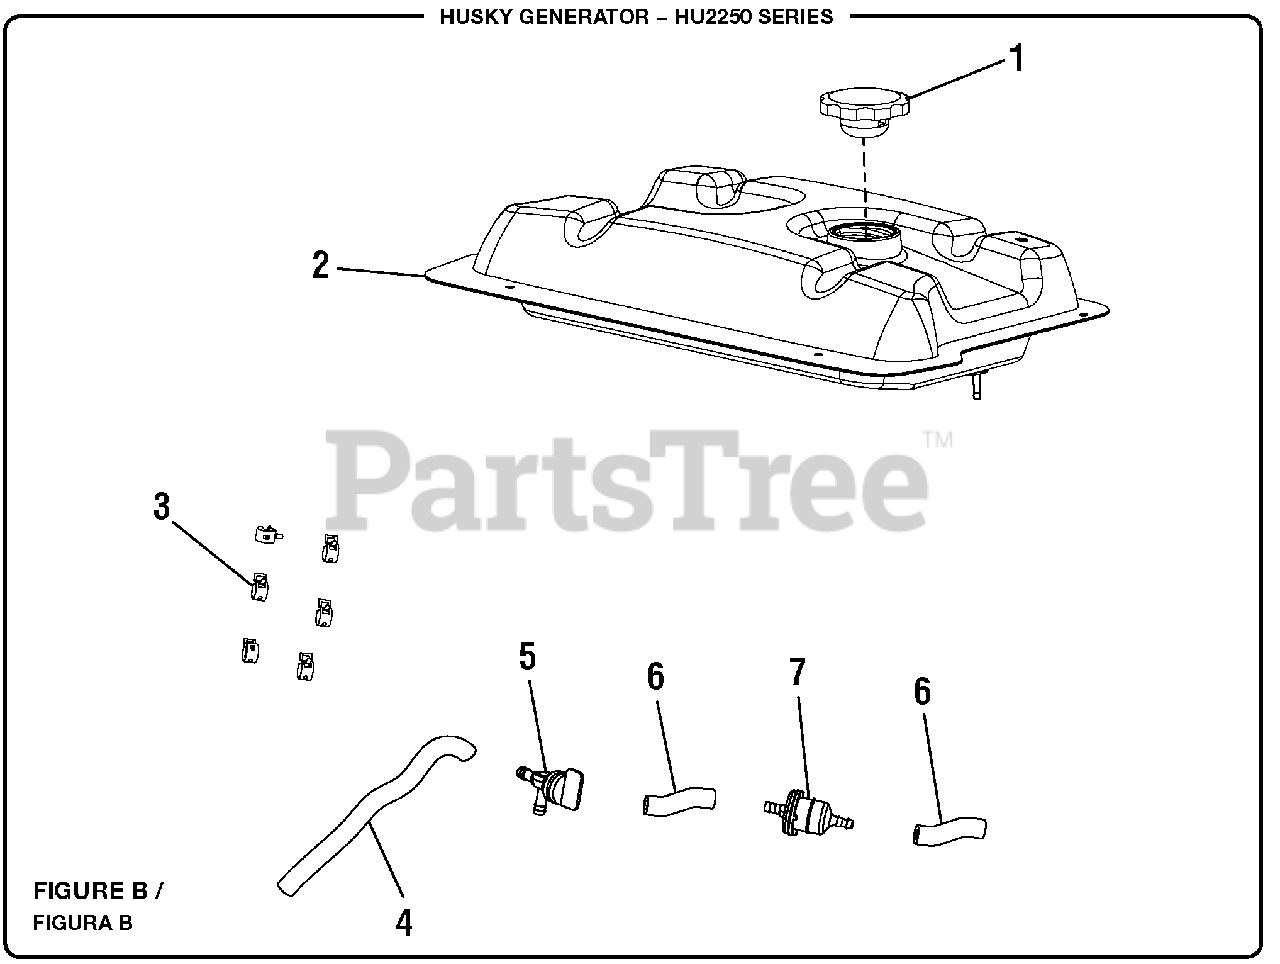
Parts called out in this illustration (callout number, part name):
1	Fuel Tank Cap
2	Fuel Tank
3	Fuel Line Clamp (1/2 in.)
4	Fuel Line Hose (150 mm)
5	Fuel Shut Off Valve
6	Fuel Hose (100 mm)
7	Fuel Line Filter
